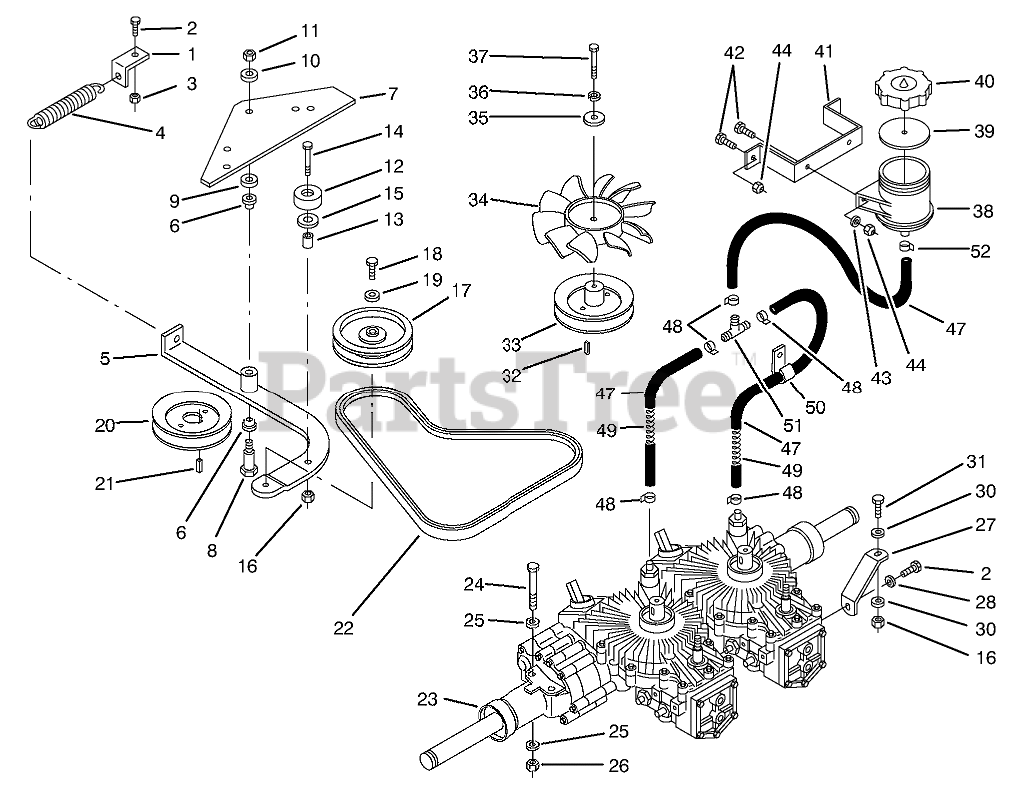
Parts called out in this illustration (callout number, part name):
1	BRACKET-SPRING
2	SCREW-HH
3	NUT-LOCK, NI
4	SPRING-EXTENSION
5	Arm-Idler
6	BUSHING
7	Stiffener
8	BOLT-SHOULDER
9	WASHER
10	WASHER-FLAT
11	NUT-HEX
12	BUMPER
13	SPACER
14	SCREW-HH
15	WASHER
16	NUT-LOCK, NI
17	PULLEY IDLER
18	SCREW-HH
19	WASHER-FLAT
20	PULLEY
22	V-BELT
23	TRANSAXLE-781
24	SCREW-HH
25	WASHER-FLAT
26	NUT-LOCK, NI
27	BRKT-HYDRO SIDE
28	Washer-Special
30	WASHER-PLAIN
31	SCREW-HH
32	KEY WOODRUFF
33	PULLEY
34	FAN-7"
35	WASHER
36	WASHER-LOCK
37	SCREW-HH
38	ASS'Y-RESERVOIR
39	COVER GASKET
40	COVER
41	Bracket
42	SCREW-HH
43	WASHER-FLAT
44	NUT-LOCK, NI
47	HOSE-7"
48	CLAMP .875
49	COMPRESSION SPRING
50	CLAMP
51	TEE-5/8 PLASTIC
52	CLAMP-HOSE
